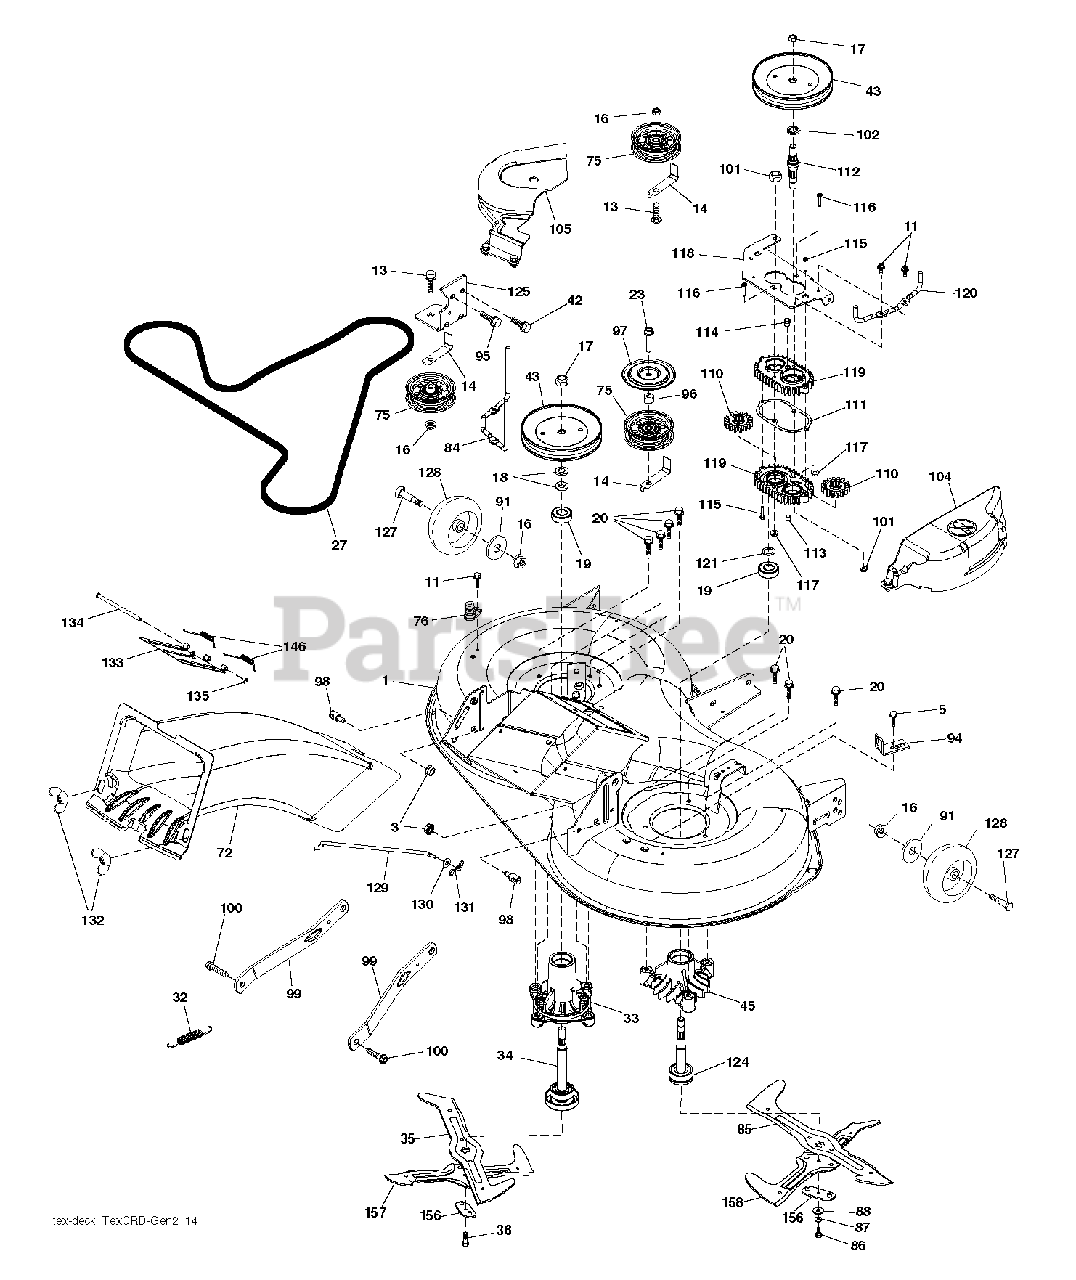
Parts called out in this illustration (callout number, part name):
3	NUT LOCK HEX FLANGE 5/16-18
5	BOLT.5/16HEX.WHS.HD
11	SCREW.1/4-20X5/8
13	BOLT.3/8-16X1.50
14	KEEPER, BELT IDLER
16	NUT LOCK FLG 3/8-16 UNC
17	NUT.FLANGE.LOCK.TOP
18	WASHER.SPACER.MANDREL
20	SCREW, WASHER HEAD
23	SCREW LT
27	BELT BELT. ELECTRIC M
32	SPRING 107CM 97CM ELE
33	HOUSING MANDREL
34	SHAFT.ASM.MDRL.N/GREASE.38
35	BLADE.3N1.LH.CRD
36	BOLT.WASHER.ASM.7/16-2
42	SCREW
43	PULLEY PULLEY MANDREL
45	HOUSING.MANDREL
72	97/107.TEX.CRD.UPPER CHUTE(22)
75	FLAT IDLER PULLEY
84	KEEPER KEEPER. LH MAN
85	BLADE.3N1.RH.CRD
86	BOLT.3/8-24X1.25GR8. LHTHRD
87	LOCKWASHER
94	BRKT.CLUTCH.CABLE
95	SCREW, 3/8-16X3/4
98	STUD.FASTNER.W/ANTI-ROTATE
99	ARM.SUSPENSION.MOWER.R
100	BOLT.SHOULDER
101	NUT.CROWNLOCK.9/16 -18.UNC
102	SPACER BEARING
110	RP.CRD.GEAR.OUTPUT
111	GASKET GASKET GEARCAS
113	PLUG PLUG OIL
114	VALVE VALVE RELIEF
115	Screw
116	BOLT.CARIGE.SS.1/4-20X1.75GR5
117	NUT T
118	ARM ARM. CLUTCHING 10
119	GEARCASE GEARCASE SUB
120	KEEPER KEEPER. RH MAN
121	Washer, .687ID X 1OD X 062 THK
124	Mandrel Shaft, Non/Greaseable
125	Bracket
127	BOLT.SHOULDER.3/8-16X3-5/8
128	WHEEL. GUAGE RALLY
129	ROD ROD. SWAY CRD GEN
130	WASHER
131	PIN.COTTER.5/16.BOW TI
132	KNOB.HANDLE.3/8.TRI-POINT.BLAC
133	COVER DOOR.107 CM CRD
134	Hinge Pin
146	SPRING SPRING EZ MULC
156	ADAPTER ADAPTER.CROSS
